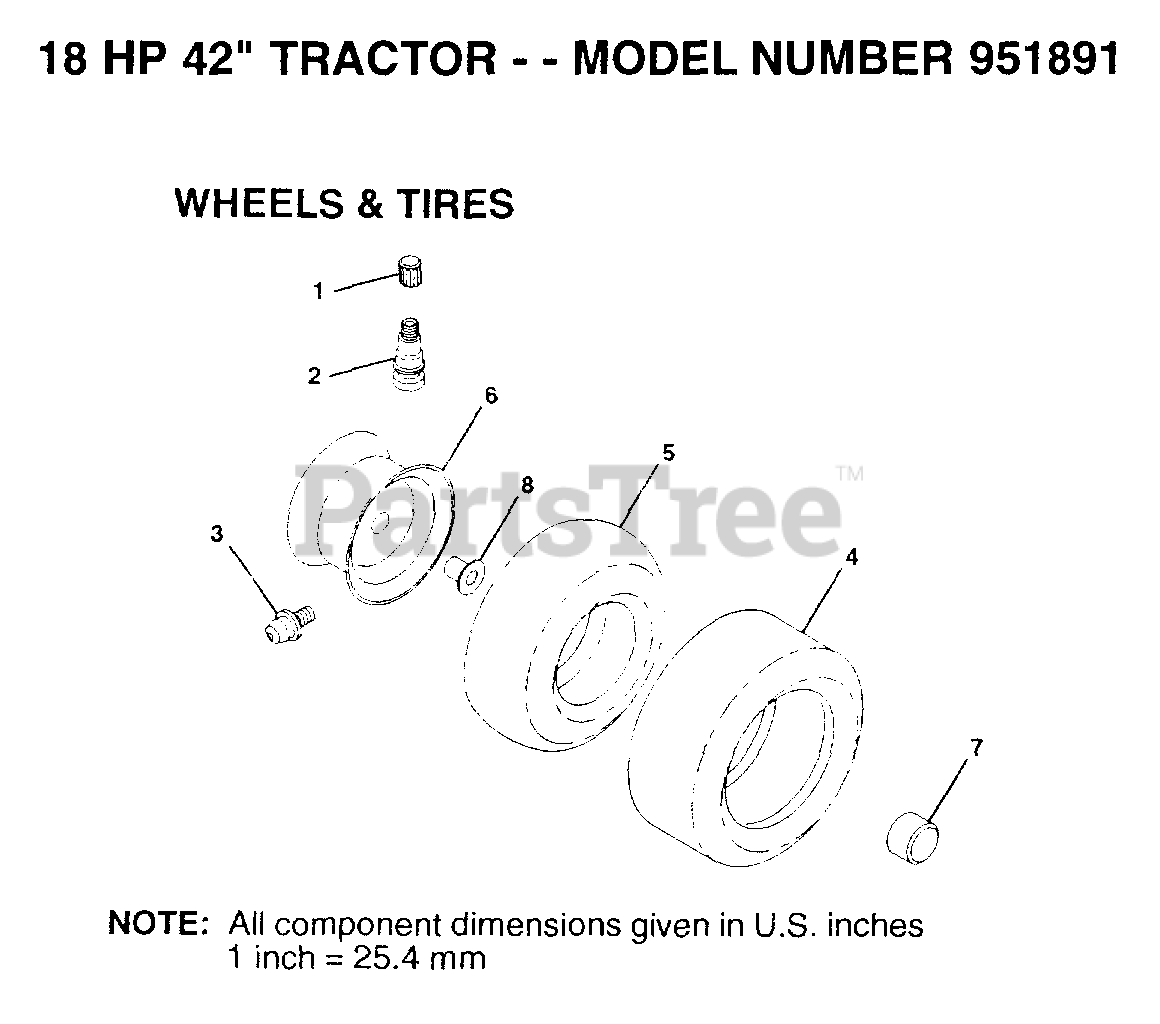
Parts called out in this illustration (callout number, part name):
1	VALVE CAP
2	VALVE STEM LT
3	FITTING LT
4	TIRE.20X8-8
5	TUBE.5.3/4.5/6
5	TUBE.18X9.5-8
7	HUB CAP
8	"FLANGE, BEARING"
